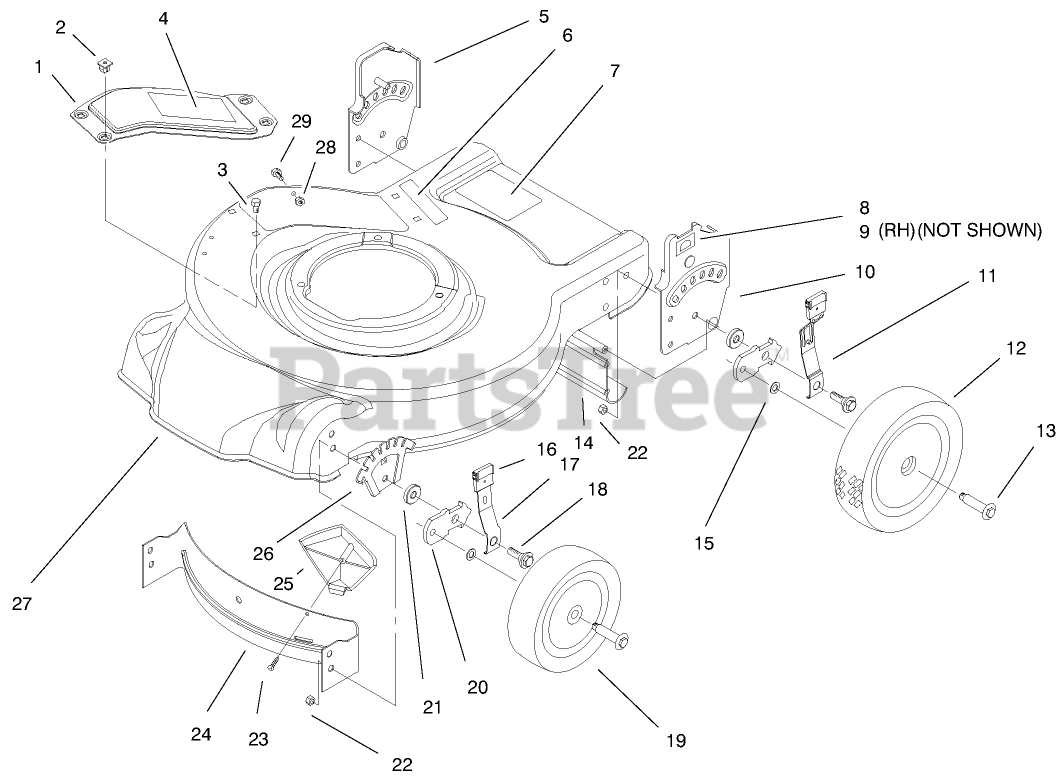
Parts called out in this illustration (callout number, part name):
1	COVER W/DECAL
3	SCREW-HWH
4	DECAL - COVER
5	ASM - RH HANDLE BRACKET
8	DECAL-HOC, RH
10	ASM - LH HANDLE BRACKET
11	REAR SPRING ARM ASM
12	WHEEL ASM
13	BOLT-SHOULDER
14	SHIELD-TRAILING
15	WASHER
16	KNOB-LEVER, HEIGHT ADJUSTMENT
17	ARM-FRONT SPRING
18	SCREW-SHOULDER, HWH
19	WHEEL ASM
21	WASHER
22	NUT-LOCK, NI
23	SCREW-PPH
25	KICKER-FRONT
28	NUT-LOCK, NI
